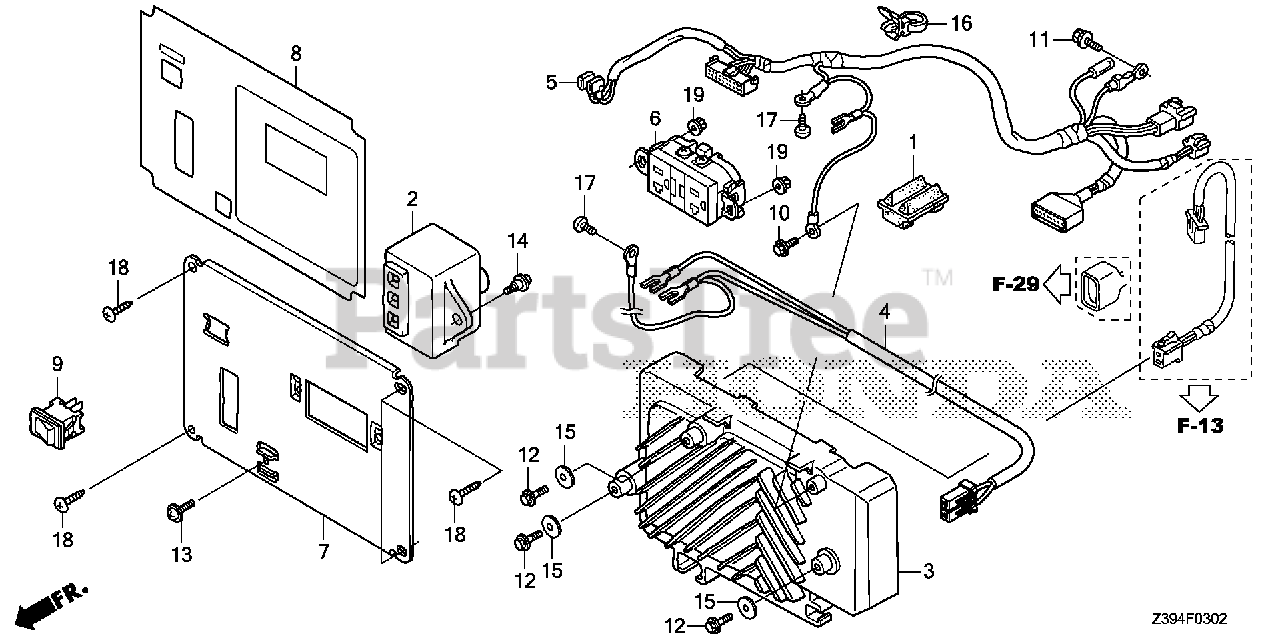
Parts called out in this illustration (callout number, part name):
1	RUBBER B, TANK MOUNTING
2	SPARK UNIT
3	INVERTER UNIT
4	SUB-WIRE HARNESS ASSY. (EB-A)
5	WIRE HARNESS ASSY., CONTROL
6	RECEPTACLE (20A-125V) (GFCI)
7	PANEL, CONTROL (EB-A)
8	MARK, CONTROL PANEL (EB-A)
9	SWITCH, AUTO-THROTTLE
9	SWITCH, AUTO-THROTTLE (OTAX)
10	BOLT, FLANGE (5X10)
11	BOLT, FLANGE (5X10) (CT200)
12	BOLT, FLANGE (5X12)
13	SCREW, PAN (5X12)
14	SCREW, PAN (5X13)
15	WASHER, PLAIN (20MM)
16	BAND (100MM) (BLACK)
17	SCREW, PAN (5X8)
18	SCREW, TAPPING (5X16) (PO)
19	NUT, FLANGE (4MM)
